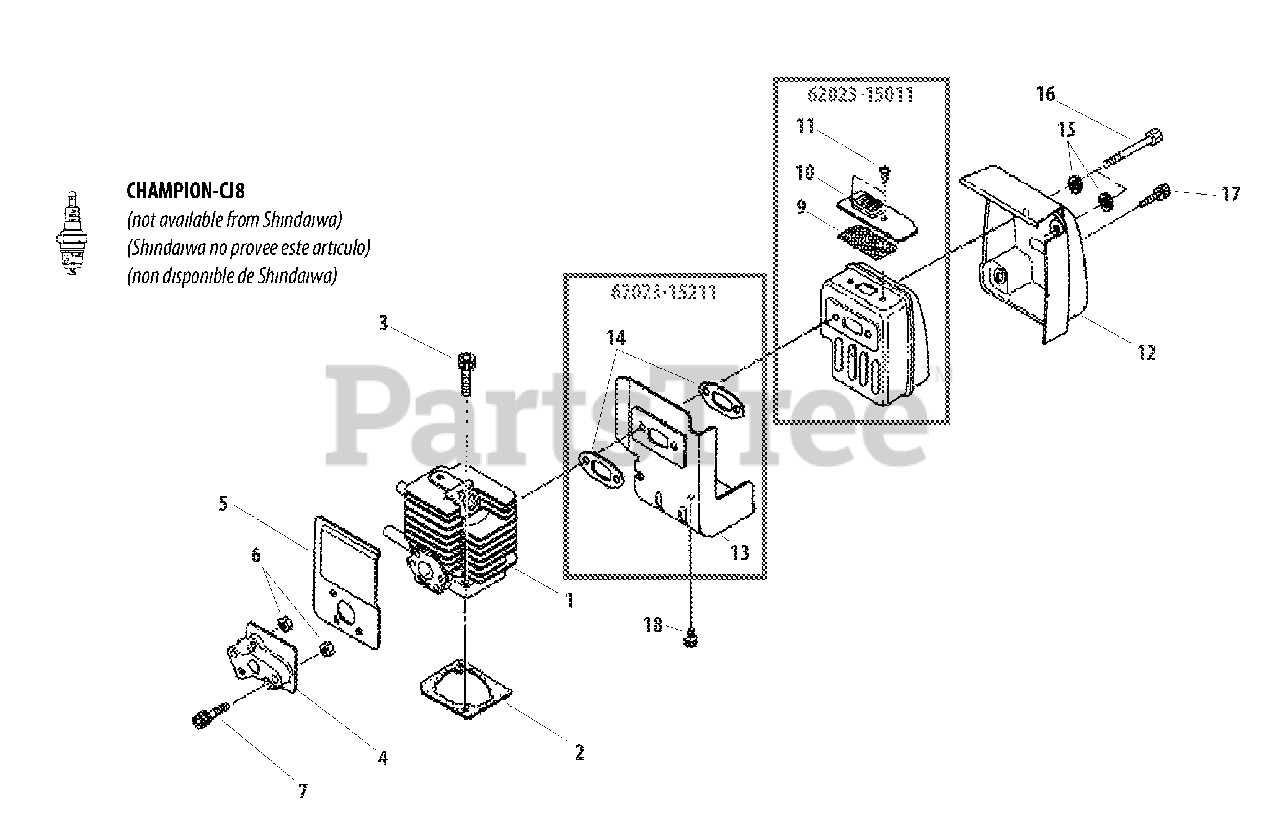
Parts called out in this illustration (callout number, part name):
1	CYLINDER
2	GASKET, CYLINDER
3	SCREW - 5X25
4	INSULATOR
5	SHIELD, INTAKE
6	NUT
7	SCREW - 5X30
9	SCREEN, SPARK ARRESTOR
10	TAIL PLATE
11	SCREW - 4X6
12	COVER, EXHAUST
13	GASKET
14	SHIELD, EXHAUST
15	WASHER - 5
16	SCREW - 5X60
17	SCREW - 5X20
18	SCREW - 5X8
62023-15011	MUFFLER ASSY
62023-15211	SHIELD, EXHAUST
